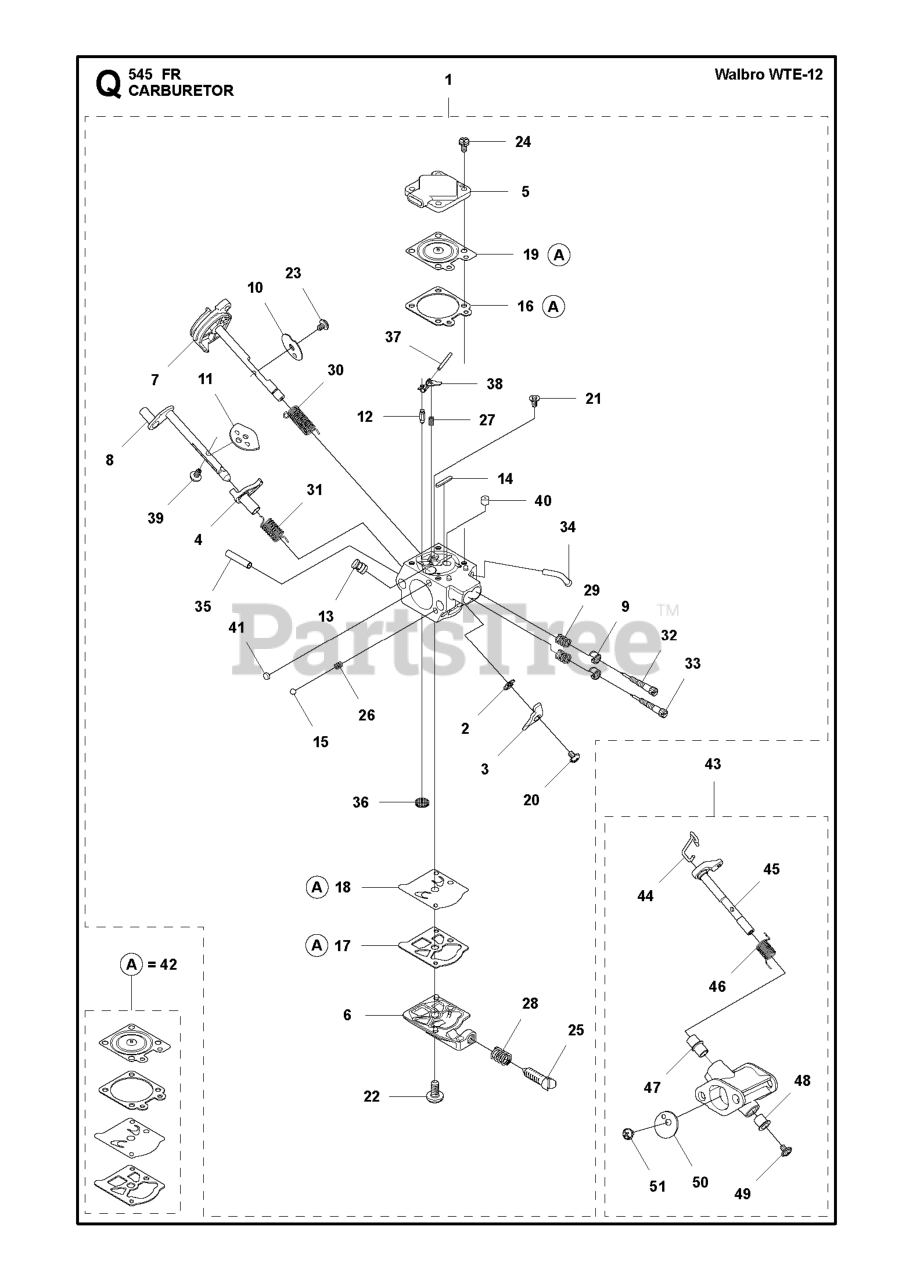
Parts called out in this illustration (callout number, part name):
1	RP CARBURETTOR ASSY
2	E CLIP
7	SHAFT ASSY
9	LIMITER CAP
10	THROTTLE FLAP
12	INLET NEEDLE
13	NOZZLE ASSY
19	DIAPHRAGM ASSY
23	SCREW
28	SPRING
36	FUEL INLET SCREEN
37	FULCRUM PIN
41	PLUG WELCH
49	SCREW
51	SCREW
